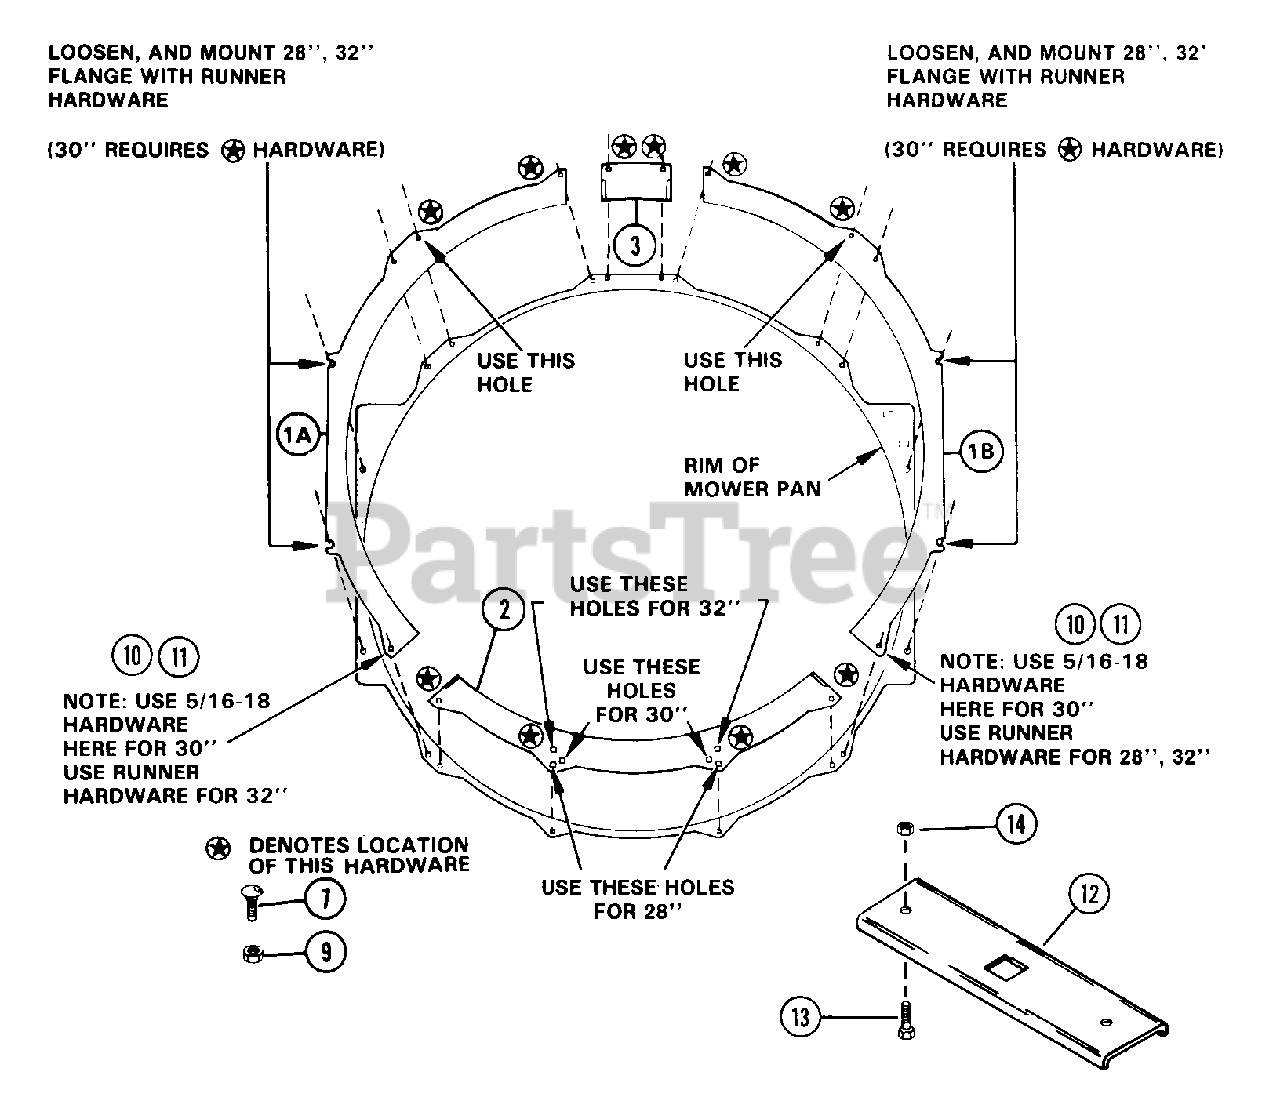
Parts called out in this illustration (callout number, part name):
1	32 IN SIDE FLANGE
2	BACK FLANGE
3	FRONT CLAMP
7	BLT-RDHDSQNK .25-20X.62 PL
9	NUT-LK-CTR .250-20 PL
